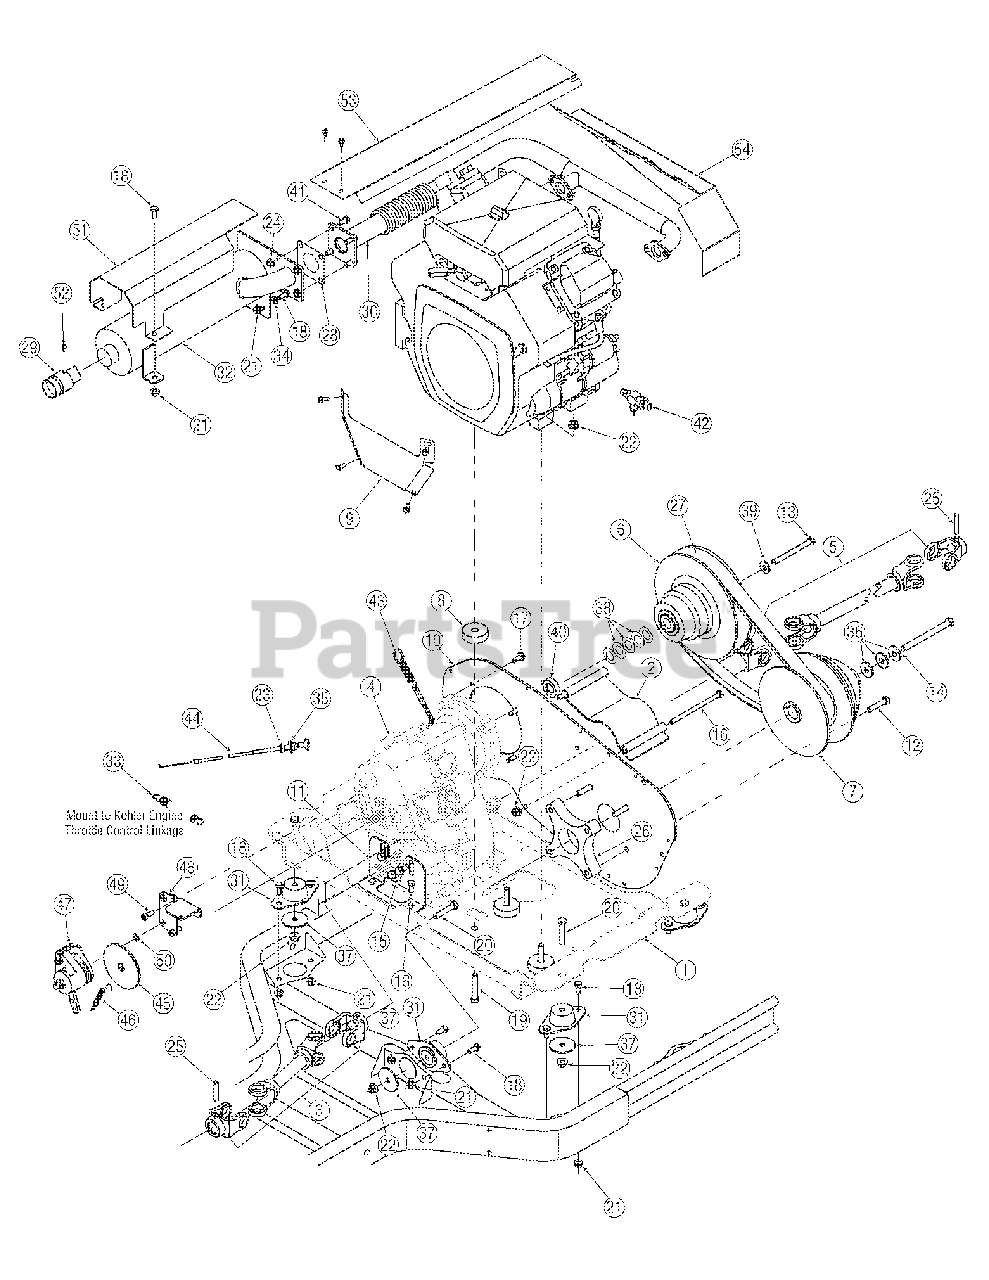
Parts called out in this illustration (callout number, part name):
1	Tray Assembly, eng, 4x4,
2	Cover, Plate, cvt
3	Shaft Assembly, rr/prop
4	Case Assembly, transfer
5	Shaft Assembly, frt/prop, Hilliard
6	Clutch Assembly, cvt, driven
7	Clutch Assembly, cvt, driver,
8	Spcr, engine, kohl, 4x4
9	Brkt, engine Shield
10	Plate, eng/trans, Kohler 20
11	Brkt, trans, mount
12	Screw, 3/8-16, 1.75, gr5,
13	Screw, 3/8-16, 4.25, Gr5,
13	Screw, 3/8-24, 4.50, Gr5,
14	Screw, 7/16-20, 5.00, gr5,
15	Scr, tt, 3/8-16, 0.750,
16	Screw, 5/16-18, 5.25, gr5,
17	Scr, ld, 5/16-18, 0.750,
18	Screw, 5/16-18, .75, gr5,
19	Screw, 3/8-16, 2.25, gr5,
20	Screw, 3/8-16, 2.00, gr5,
21	Nut, flglk, 5/16-18, grf, nylon
22	Nut, flglk, 3/8-16, grf, nylon
23	Nut, jam, 3/8-24, gr5
24	Nut, flglk, 5/16-18, gr5, sd
25	Pin, spirol, 5/16, 1.75
26	Spcr, eng/trans Plt, mount,
27	Belt, cvt, 4x4
28	Gskt, eng, 4x4
29	Arstr, scrn, spark
30	Pipe, exh, kohl 4x4
31	Mt, comprs, eng, hd
32	Muffler, 4x4, cat/khlr
33	Spring .50 Od X 4.5
34	Washer, flat, .330 X .630
35	Washer, flat, .406 X .875 X
36	Washer, flat, .450x1.250x.164,
37	Washer, flat, .38 X 2.00 X
38	Washer, fl, .793x1.368 X.025,
39	Washer, Bell, .396 x 1.14 X
40	Spcr, 20mm X 1.50 X .37
41	Screw, 5/16-18 x .875
42	Valve, Oil Drain
43	Kit, Throttle Cable
44	Cbl, cont, choke, 4x4 Kohl
45	Disc, Brake, UV
46	Spr., Ext., .38OD x 3.9
47	Brake Assembly, Transfer
48	Brake, Brake Mounting
49	Screw, Soc. Hd. 5/16-18 x
50	Washerer, Flat, .385 x .62
51	Heat Shield, Exhaust
52	Screw, Hex #8-32 x .375
53	Cover, Heat Shield
54	Cover, Engine Shield
